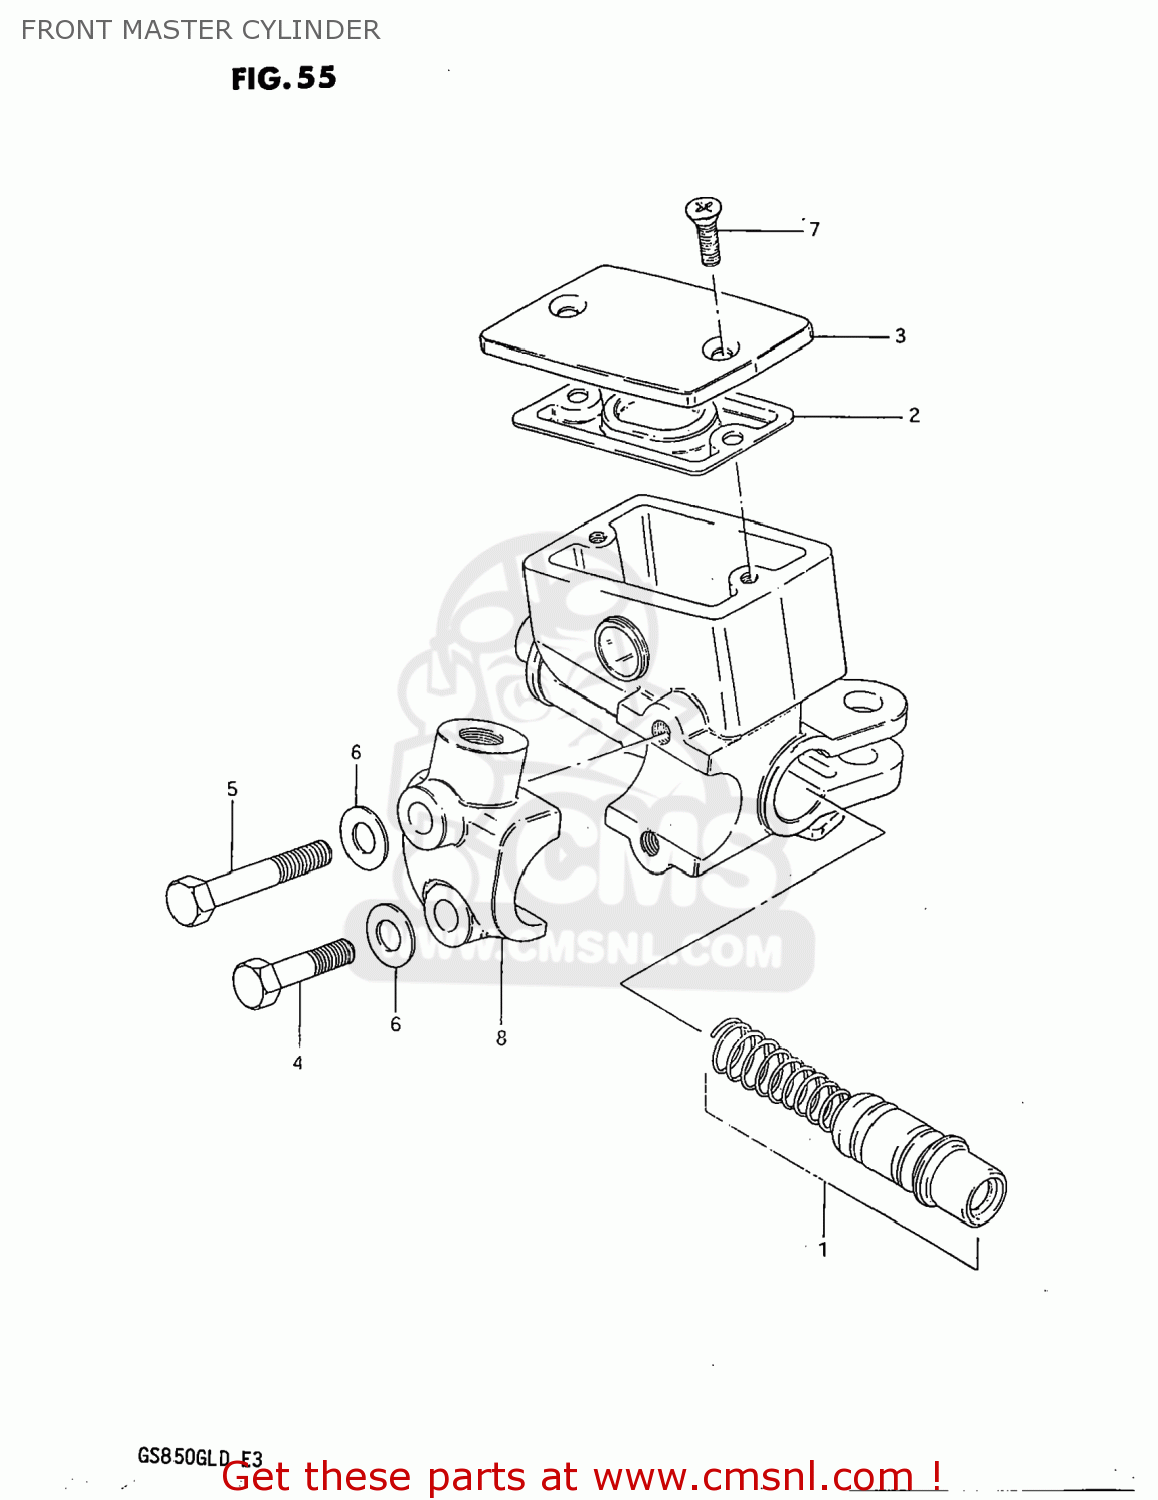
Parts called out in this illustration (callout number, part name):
1	PISTON & CUP SET
2	3
3	CAP
4	BOLT
5	BOLT 6X40
6	WASHER
7	SCREW
8	HOLDER
